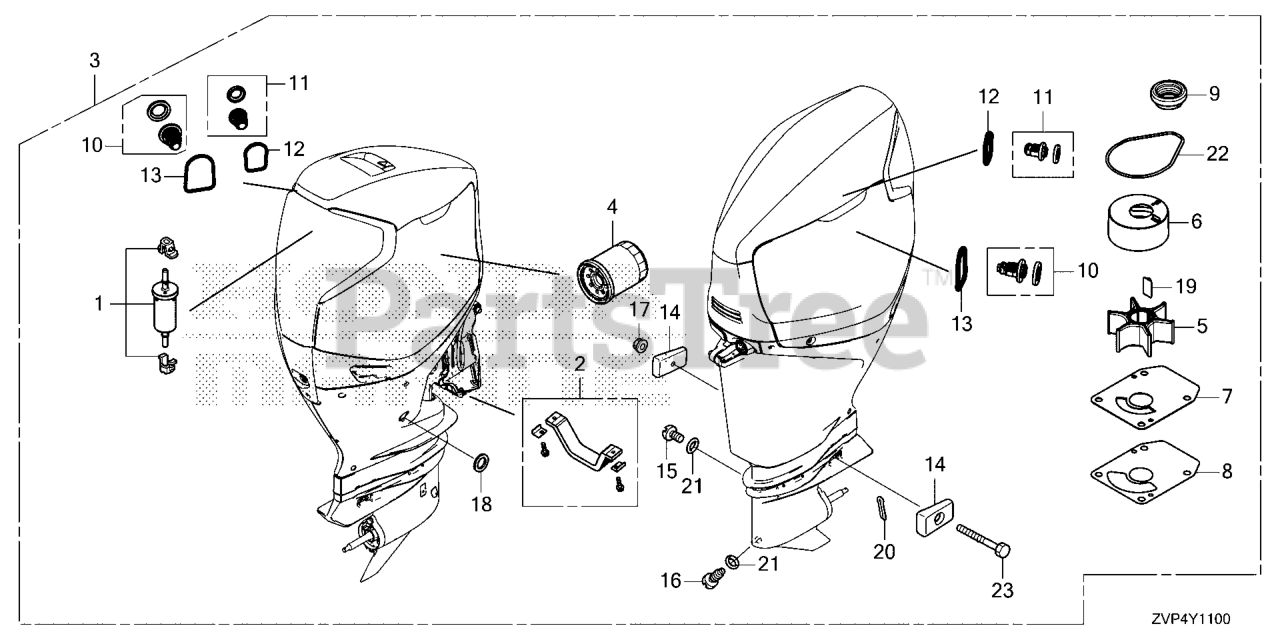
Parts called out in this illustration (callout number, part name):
1	FILTER ASSY., FUEL (HIGH)
2	METAL KIT, ANODE
3	MAINTENANCE KIT (200)
4	FILTER, OIL
5	IMPELLER, PUMP
6	LINER, WATER PUMP
7	COVER, IMPELLER
8	GASKET B, IMPELLER
9	RING
10	THERMOSTAT ASSY.
11	THERMOSTAT ASSY.
12	PKG
13	PKG
14	METAL, ANODE
15	BOLT, OIL CHECK
16	BOLT, DRAIN PLUG
17	NUT, SELF-LOCK (6MM)
18	WASHER, DRAIN PLUG (12MM)
19	KEY, WOODRUFF
20	PIN, SPLIT (4.0)
21	O-RING (6.9X1.45)
22	O-RING, WATER PUMP
23	BOLT, HEX. (6X50)
